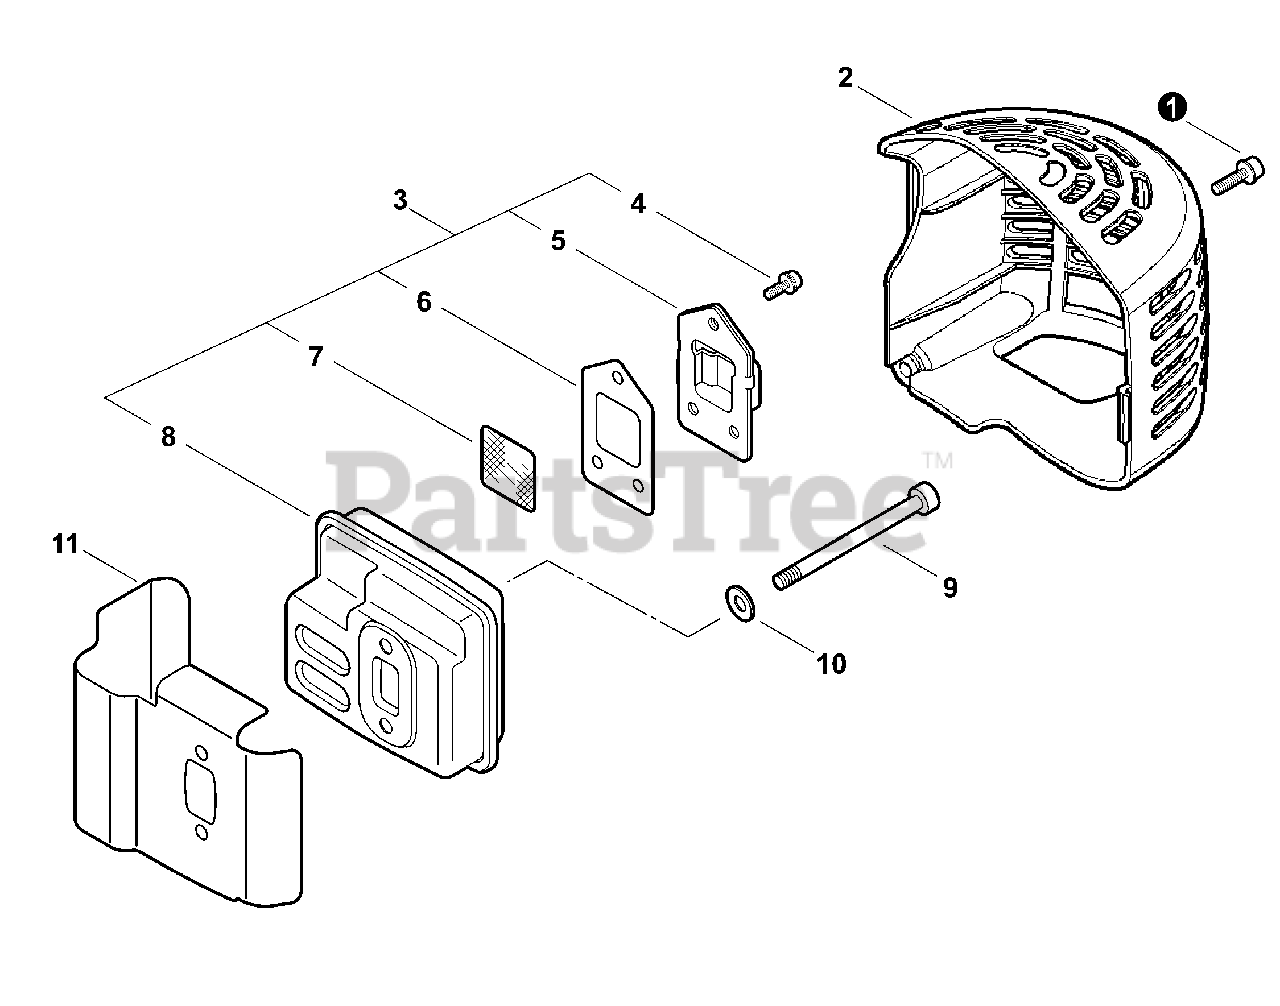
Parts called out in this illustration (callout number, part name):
1	BOLT 5×16
2	COVER, MUFFLER
3	SCREW 4×10
4	GUIDE, EXHAUST
5	GASKET, EXHAUST
6	SCREEN, SPARK ARRESTER
7	BOLT 5×55
8	WASHER, FLAT 5.5×10×0.8
10	HEAT SHIELD, EXHAUST
